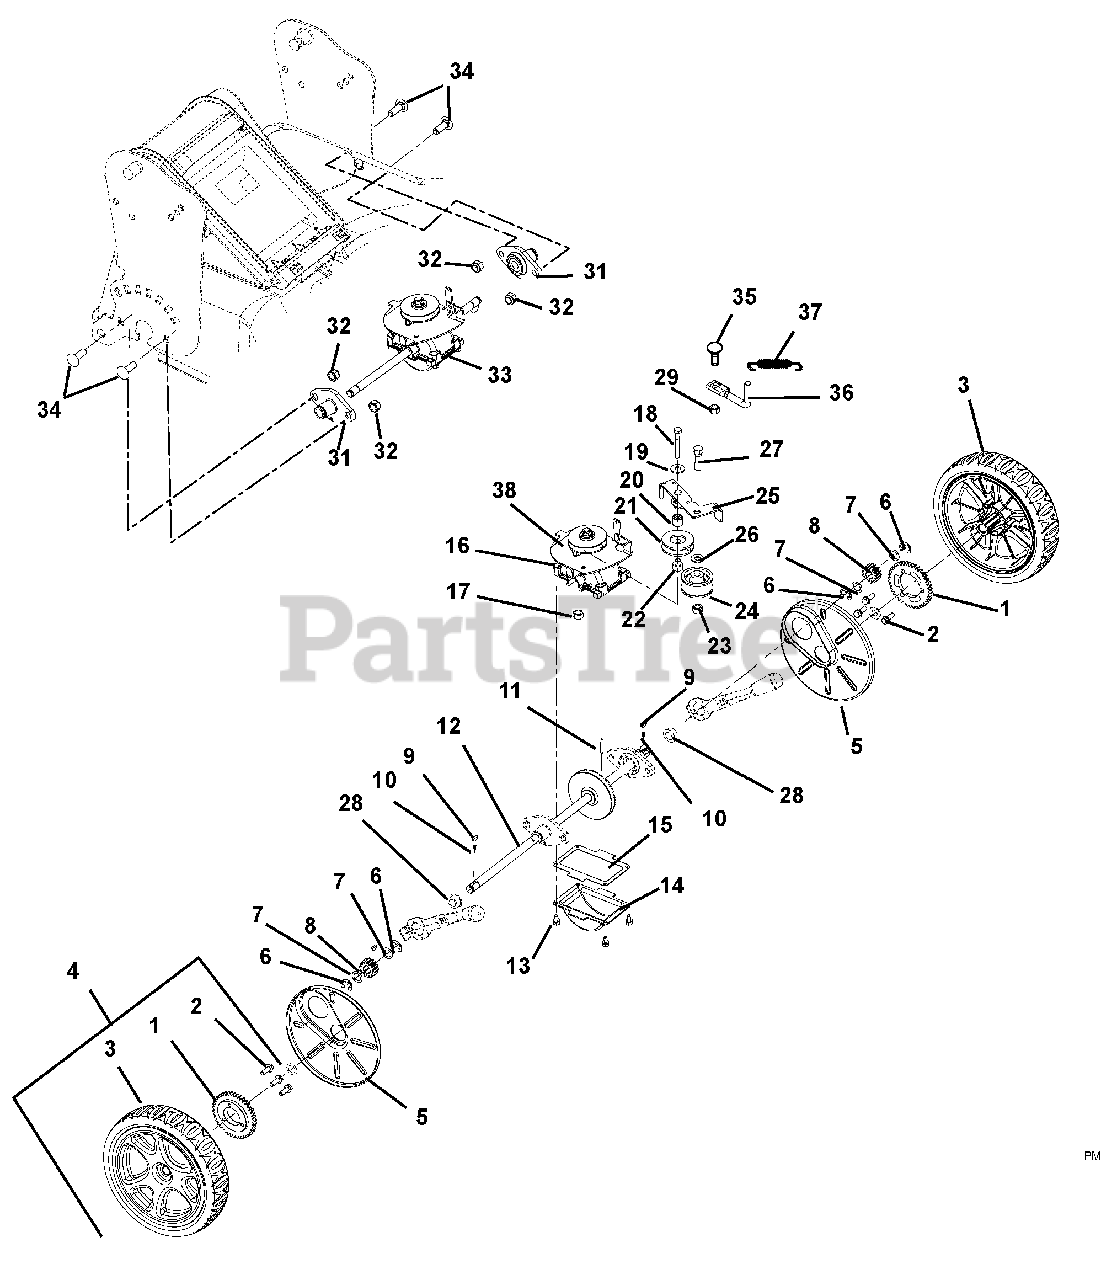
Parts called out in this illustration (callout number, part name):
1	GEAR, WHEEL
2	SCR-TAP .25-15X.75 HI-LO
3	WHEEL, 8.5" WBLM
4	ASSY, LM REAR WHEEL
5	WHEEL COVER
6	RG-RTNG-EXT .500X.042 (E)
7	WASHER, .500X.750X.020 THRUST
8	PINION, WBLM DRIVE
9	KEY-WDRF .125X.50X.20 (HRDEND)
10	SPRING, .134X.180X.144 COMP.
12	SHAFT, TRANSMISSION OUTPUT
13	@SCR-TAP 10-24X.375 HWH YZ TR
14	SUMP, GEARBOX
15	GASKET, TRANSMISSION
16	KIT, WBLM TRANS HOUSING
17	@NUT-LK-TOP-FLG .25-20 YWZC
18	BLT-HEX .25-20X2.25 GR8 YWZC
19	@WSHR-FL-STL.312X.734X.065 YWZ
20	SPACER, IDLER ARM
21	IDLER, 3L FRONT SIDE .38X1.875
22	SPACER, V-IDLER PULLEY
23	@NUT-LK-CTR .38-16 YWZC
24	IDLER - FLAT 1.875OD X .75WIDE
25	ARM, TRANSMISSION IDLER
26	@WSHR-FL-STL.406X.812X.065 YWZ
27	@BLT-HEX .38-16X1.38 GR5 YWZC
28	BUSHING, TRANS OUTPUT SHAFT
29	@NUT-SPNLK-FLG .25-20 YWZC
30	BRACKET, TRANSMISSION CONTROL
31	KIT, WHEEL MOUNT HUB SERVICE
32	@NUT-LK-TOP-FLG .31-18 YWZC
33	KIT, TRANSMISSION SERVICE
34	@BLT-RDHDSQNK .31-18X1.00 G5YZ
35	@BLT-RDHDSQNK .25-20X.50 G5YZ
36	FINGER, BELT
37	SG-TENS .051X.60X2.25 WLD 7.0
38	PLATE, WHEEL GEAR TORQUE
